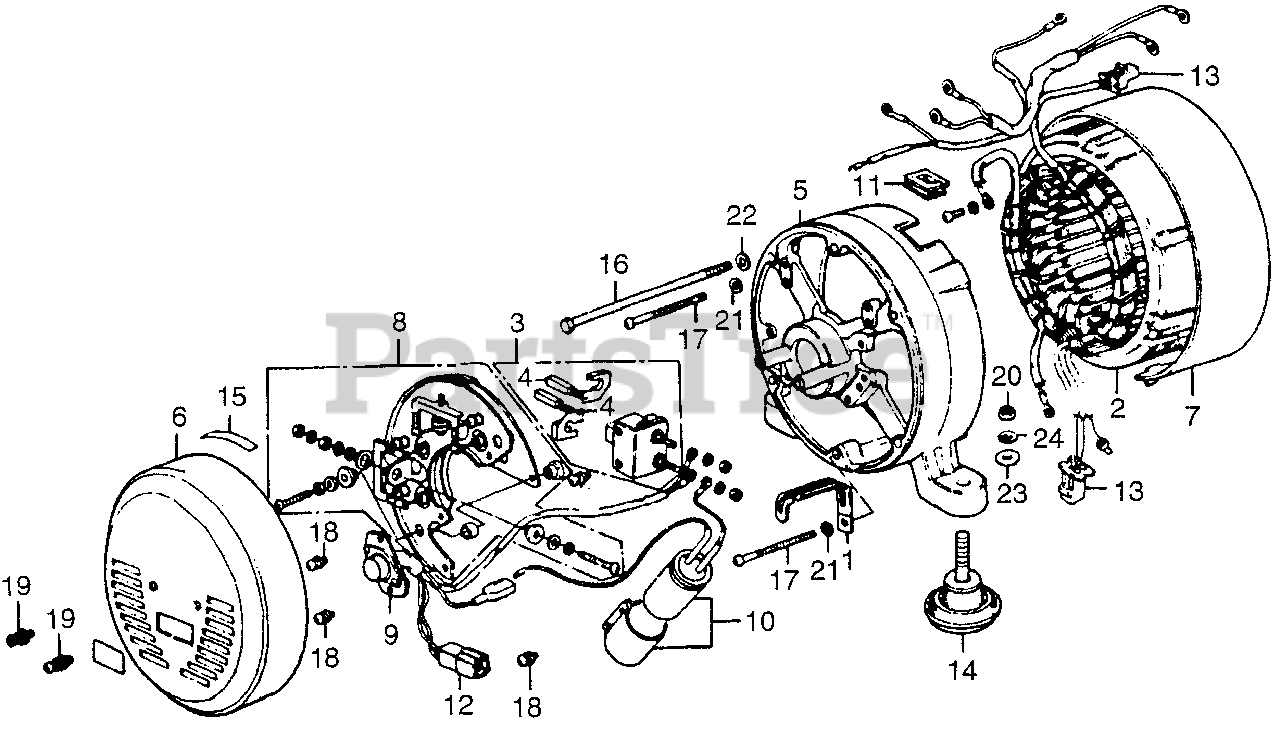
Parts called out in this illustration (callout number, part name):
1	CLAMP A, WIRE
2	STATOR ASSY.
3	HOLDER, BRUSH
5	HOUSING, RR. *R8* (BRIGHT RED) (NOT AVAILABLE)
6	COVER, GENERATOR END *R8* (BRIGHT RED)
7	COVER, STATOR *R8* (BRIGHT RED)
8	DIODE ASSY. (NOT AVAILABLE)
9	STACK ASSY., DIODE (NOT AVAILABLE)
10	CONDENSER ASSY.
12	CONNECTOR, MALE (2 POLE)
13	CONNECTOR, FEMALE (2 POLE) (NOT AVAILABLE)
14	RUBBER (LOWER)
15	MARK C, CAUTION (NOT AVAILABLE)
16	BOLT, HEX. (6X142)
17	SCREW, PAN (5X10)
18	SCREW, PAN (5X55) (NOT AVAILABLE)
19	SCREW-WASHER (5X10)
20	NUT, HEX. (8MM)
21	WASHER, PLAIN (5MM)
22	WASHER, PLAIN (6MM)
23	WASHER, PLAIN (8MM)
24	WASHER, SPRING (8MM)
